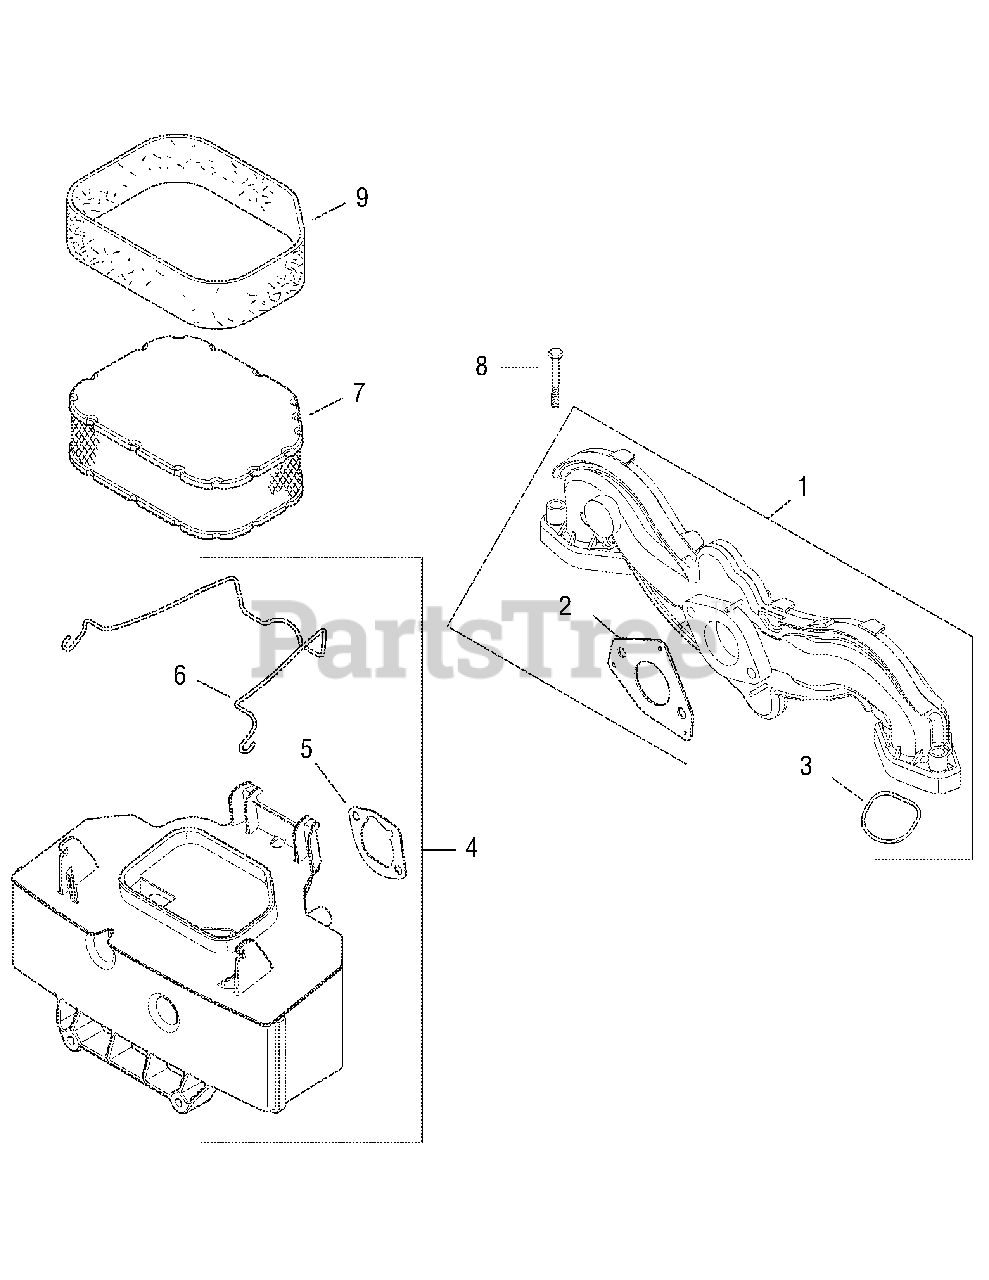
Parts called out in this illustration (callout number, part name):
1	Manifold, intake (Includes 2,3)
2	Gasket, carburetor
3	O-Ring, intake port
4	Base, air cleaner (Includes 5,6)
5	Gasket, air cleaner base
6	Latch, air cleaner element
7	Element, air cleaner
8	Screw, hex. flange M6x1.0x40
9	Pre-cleaner, element
